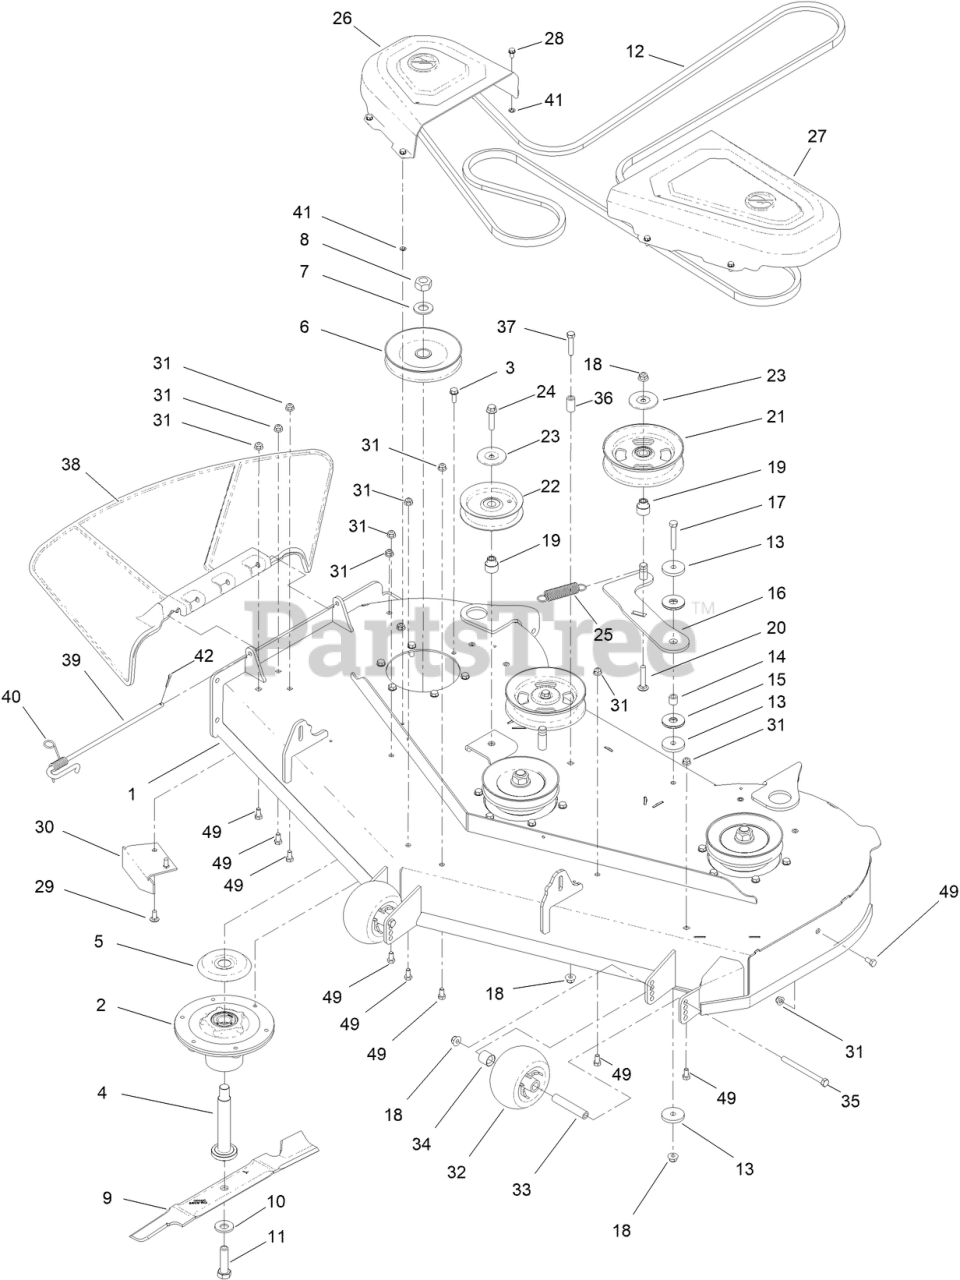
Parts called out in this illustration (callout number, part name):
1	DECK ASM-54"
2	SPINDLE ASM
3	SCREW-TAPTITE
4	SHAFT-SPINDLE
5	SHIELD-BEARING
6	PULLEY
7	WASHER
8	NUT-HEX
9	BLADE - HI FLOW, 18.75 IN
10	WASHER-BELLEVILLE
11	SCREW-BLADE
12	BELT-V
13	WASHER-PLAIN
14	BUSHING-IDLER
15	WASHER-FRICTION, COMPOSITE
16	IDLER ARM ASM
17	SCREW-HH
18	NUT-HF, NI
19	BUSHING-IDLER
20	SCREW-CARR
21	PULLEY-IDLER, FLAT
22	PULLEY-IDLER, FLAT
23	SHIELD-DUST
24	SCREW-HHF
25	SPRING-EXTENSION
26	COVER-BELT, RH
27	COVER-BELT, LH
28	SCREW-HWH
29	SCREW-CARR
30	BAFFLE-CUTOFF
31	NUT-HF, NI
32	ROLLER-SCALP, ANTI
33	TUBE-SPANNER
34	SPACER-AXLE, REAR
35	SCREW-HH
36	SPACER-FENDER
37	SCREW-HH
38	DEFLECTOR-DISCHARGE
39	PIN-CHUTE
40	SPRING-TORSION
41	NUT-RETAINING
42	PIN-COTTER
49	SCREW-HH
